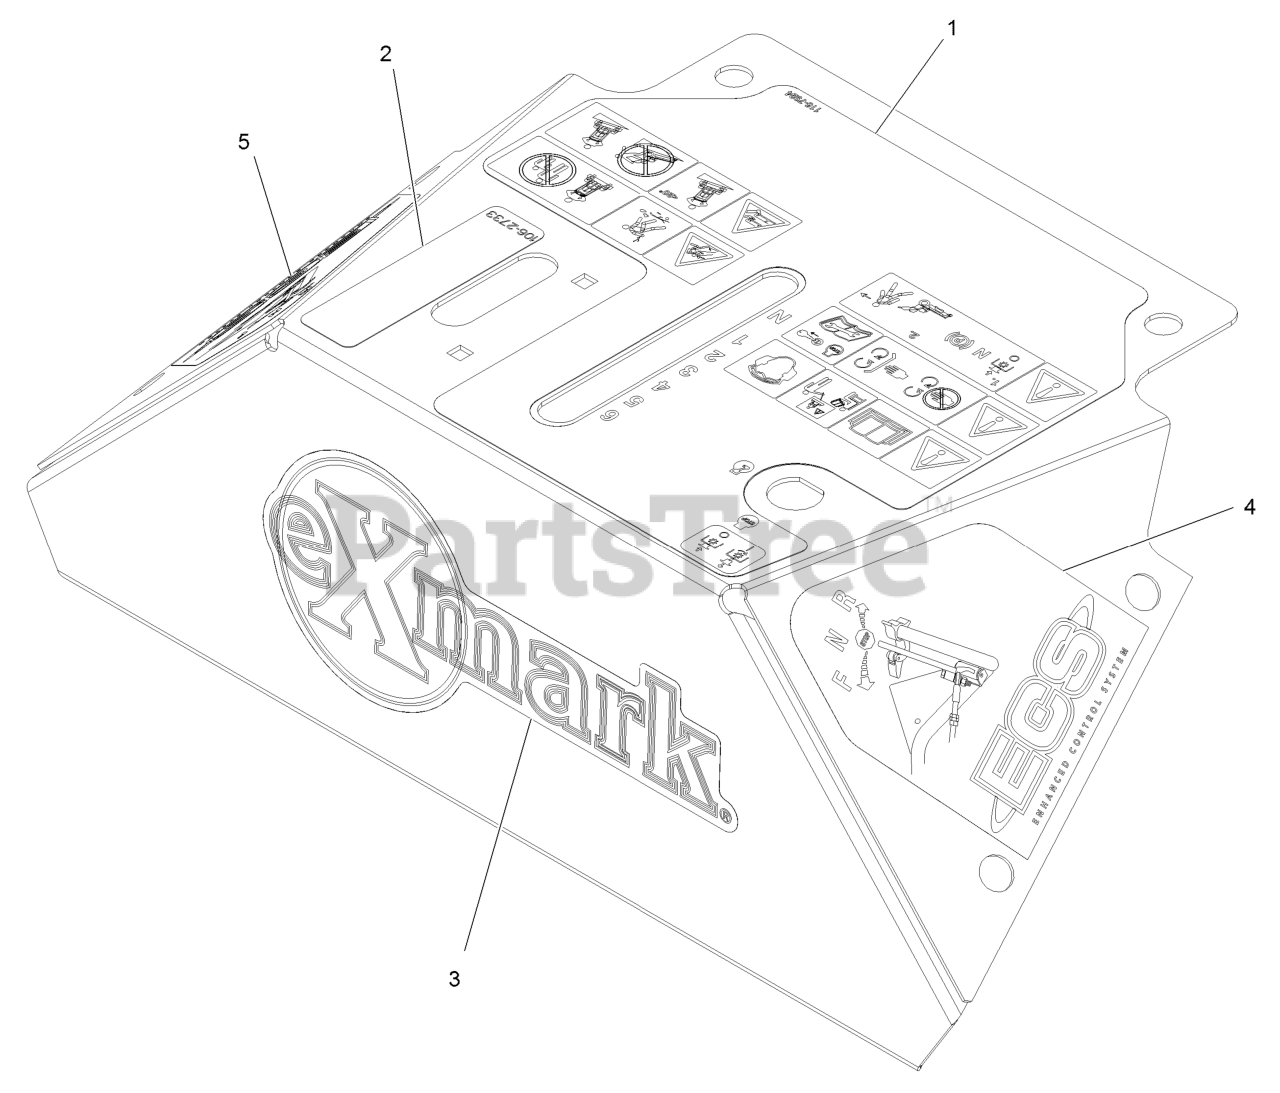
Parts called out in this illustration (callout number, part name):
1	Decal-Console Vh Ecs
2	DECAL-THROTTLE
3	DECAL, EXMARK LOGO
4	DECAL,LH ECS INSTRUCTION
5	DECAL,RH ECS INSTRUCTION
